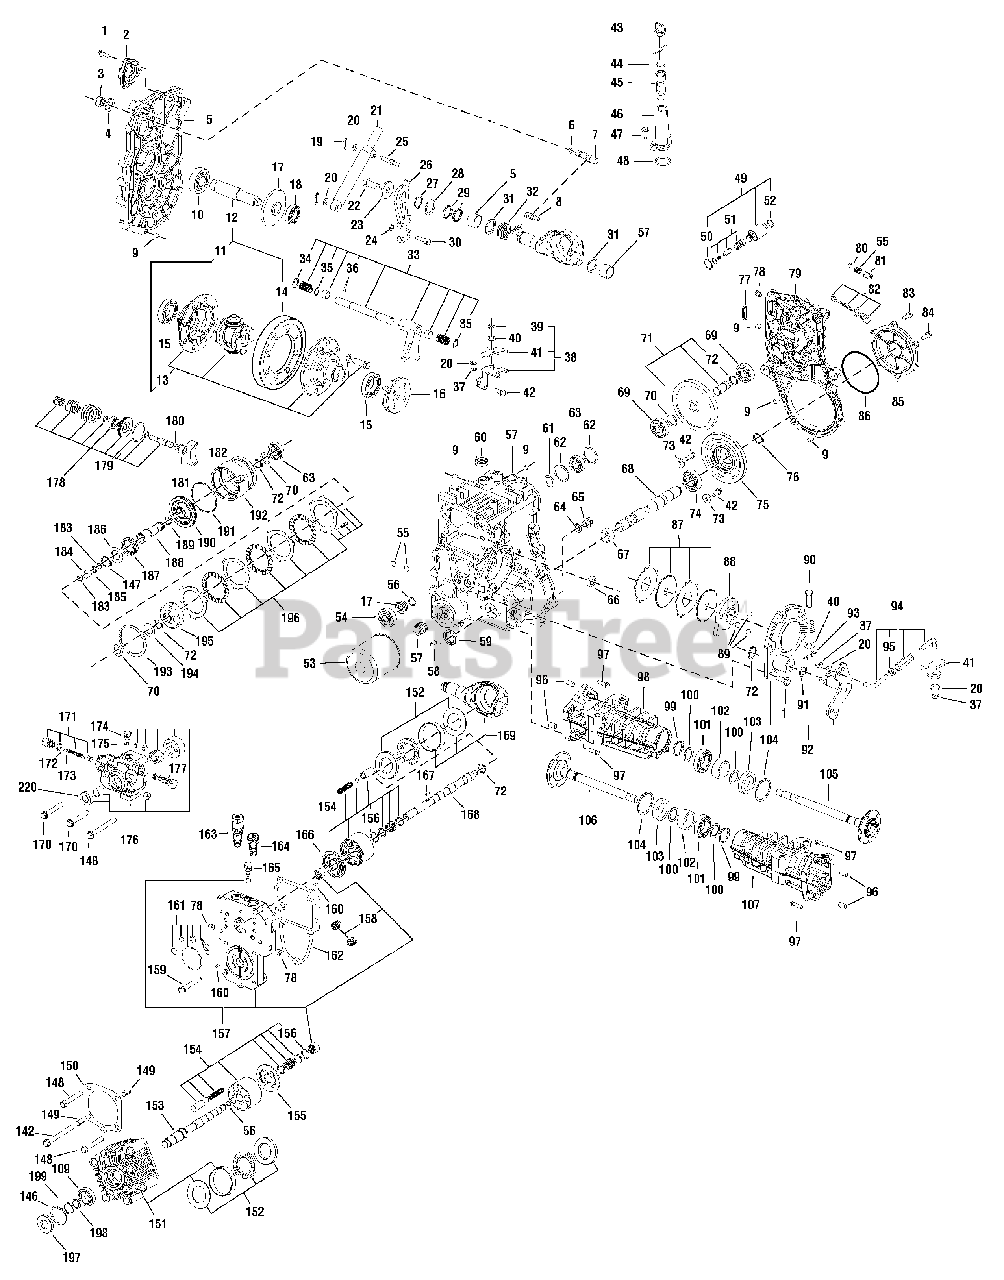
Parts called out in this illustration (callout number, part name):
2	COVER PTO BRAKE
5	COVER KIT MISSION
6	O-RING, 1A P10A
8	SPRING CENTERING
9	COLLAR 8*10*11.5
10	BEARING TMB305
11	FINAL GEAR KIT
12	SHAFT FINAL PINION
13	DIFF GEAR KIT
15	BEARING 6007
16	SLIDER DIFF LOCK
17	GEAR KIT INPUT
18	BEARING 6005SH2
21	ABSORBER SHOCK
23	WASHER 44*14*4.5
24	PUSH NUT 7.8
26	ARM CONTROL
28	WASHER 29*35*1
29	PACKING P26
30	PIN ARM CONTROL
31	WASHER 38*38*2
33	FORK KIT DIFF LOCK
34	SPACER 16.5*24*1
36	PIN 4.0A*25
38	FULCRUM KIT DIFF
44	PACKING P18
45	PIPE OIL PORT
47	TAPPING SCREW 8*20
48	PACKING P32
49	SOLENOID ASSY
50	GASKET SOLENOID
51	VALVE ASSY SOLENOID
52	PACKING P18
54	BEARING TMB303C
56	RING 12*1.6
57	HOUSING KIT MISSION
59	SEAL TC253807
61	PACKING 19017
63	BEARING 6004
66	SEAL TC162606
67	NEEDLE 253216 NTN
68	SHAFT MID PTO
69	BEARING 6204
71	IDLE ASSY PTO
73	WASHER 8.5*24*4
74	BEARING 6205 NTN
75	GEAR Z=62T MID PTO
81	SOLENIOD SPRING
82	PTO RELIEF VALVE KIT
85	REAR COVER PLATE
86	PACKING G130
87	PLATE KIT BRAKE
91	PACKING P16
92	CAM BRAKE KIT
96	COLLAR 10*12*20
98	REAR AXLE HOUSING R
100	COLLAR 30*42*2
101	BEARING 6006 NTN
102	SLEEVE 30*39*16
103	SEAL TC395511
105	SHAFT REAR AXLE R
106	SHAFT REAR AXLE L
107	REAR AXLE HOUSING L
109	BEARING 6203
148	BOLT 10*105
149	PIN KNOCK 12*22
150	PACKING MOTOR CASE
151	CASE MOTOR CMP
152	BEARING SET THRUST
153	SHAFT MOTOR
154	BLOCK ASSY CLYL. P
155	PLATE VALVE M
157	CENTERCASE ASSY
158	BODY ASSY SUCTION
161	PACKING KIT
162	CENTERCASE PACKING
163	RELIEF ASSY TOW 32
164	VALVE ASSY CHECK R
165	RELEASE ASSY IMPLE
166	PLATE VAVLE P
174	PLUG 1/2-2OUNF
175	PACKING AS 905
176	BODY ASSY PUMP
177	VAVLE ASSY REDUCING
178	BRAKE KIT PTO
179	PACKING 2045
180	PACKING P10
181	COLLAR BRAKE PIN
182	SHOE PTO BRAKE
184	NEEDLE 121718
185	WASHER 13*17*1
186	WASHER 25*42*2
187	SPRING PTO RETURN
188	SHAFT CLUTCH
189	RING SEAL 17203
191	PACKING G75
192	GEAR CLUTCH Z=39
194	WASHER 20*34*1
195	COLLAR SPLINE
196	DISC KIT FRICTION
197	SEAL CAP 40
198	WASHER 17*23*1
220	SEAL, Charge Pump
